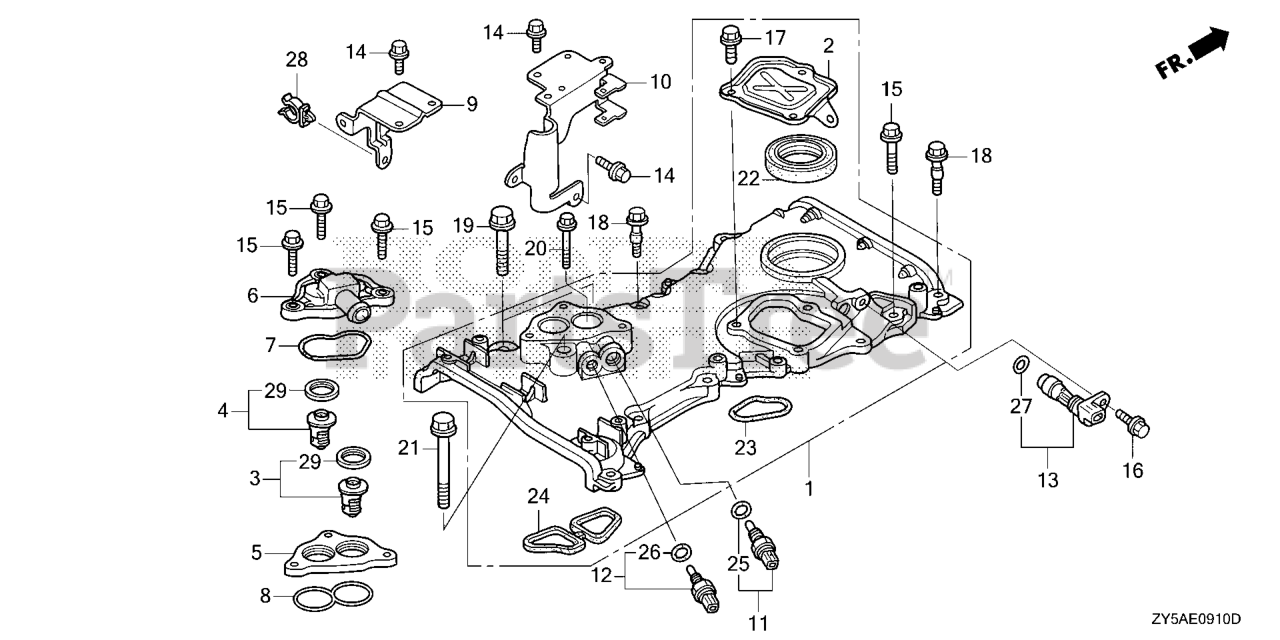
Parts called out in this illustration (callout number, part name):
1	CASE, CHAIN *NH8*
1	CASE ASSY., CHAIN *NH8* (DARK GRAY)
2	COVER, CHAIN CASE
3	THERMOSTAT ASSY.
4	THERMOSTAT ASSY.
5	SPACER KIT, THERMOSTAT COVER
5	SPACER, THERMOSTAT COVER
6	COVER, THERMOSTAT
7	GASKET, THERMOSTAT COVER
8	GASKET, THERMOSTAT SPACER
9	BRACKET B, HARNESS CLIP
10	BRACKET C, HARNESS CLIP
11	SENSOR ASSY., WATER TEMPERATURE
12	SENSOR ASSY., WATER TEMPERATURE
13	SENSOR ASSY., CRANK
14	BOLT, FLANGE (6X14) (CT200)
15	BOLT, FLANGE (6X28)
16	BOLT, FLANGE (6X16)
17	BOLT, FLANGE (6X14)
18	BOLT, SPECIAL (6X31)
19	BOLT, FLANGE (10X43)
20	BOLT, FLANGE (6X38)
21	BOLT, FLANGE (10X70)
22	OIL SEAL (43X58X7) (ARAI)
23	O-RING, CHAIN CASE
24	GASKET, CHAIN CASE
25	O-RING (9.5X1.5) (HONDA KIKAKI)
26	O-RING (9.5X1.9)
27	O-RING (15X1.9)
28	CLAMP (18.5MM)
29	RUBBER, RING
30	CASE KIT, CHAIN
31	SUB-WIRE HARNESS ASSY. (A)
32	SUB-WIRE HARNESS ASSY. (B)
33	BRACKET, SUB-HARNESS CLIP
34	BAND, WIRE HARNESS
35	CLIP, HARNESS BAND (145MM) (BLACK)
